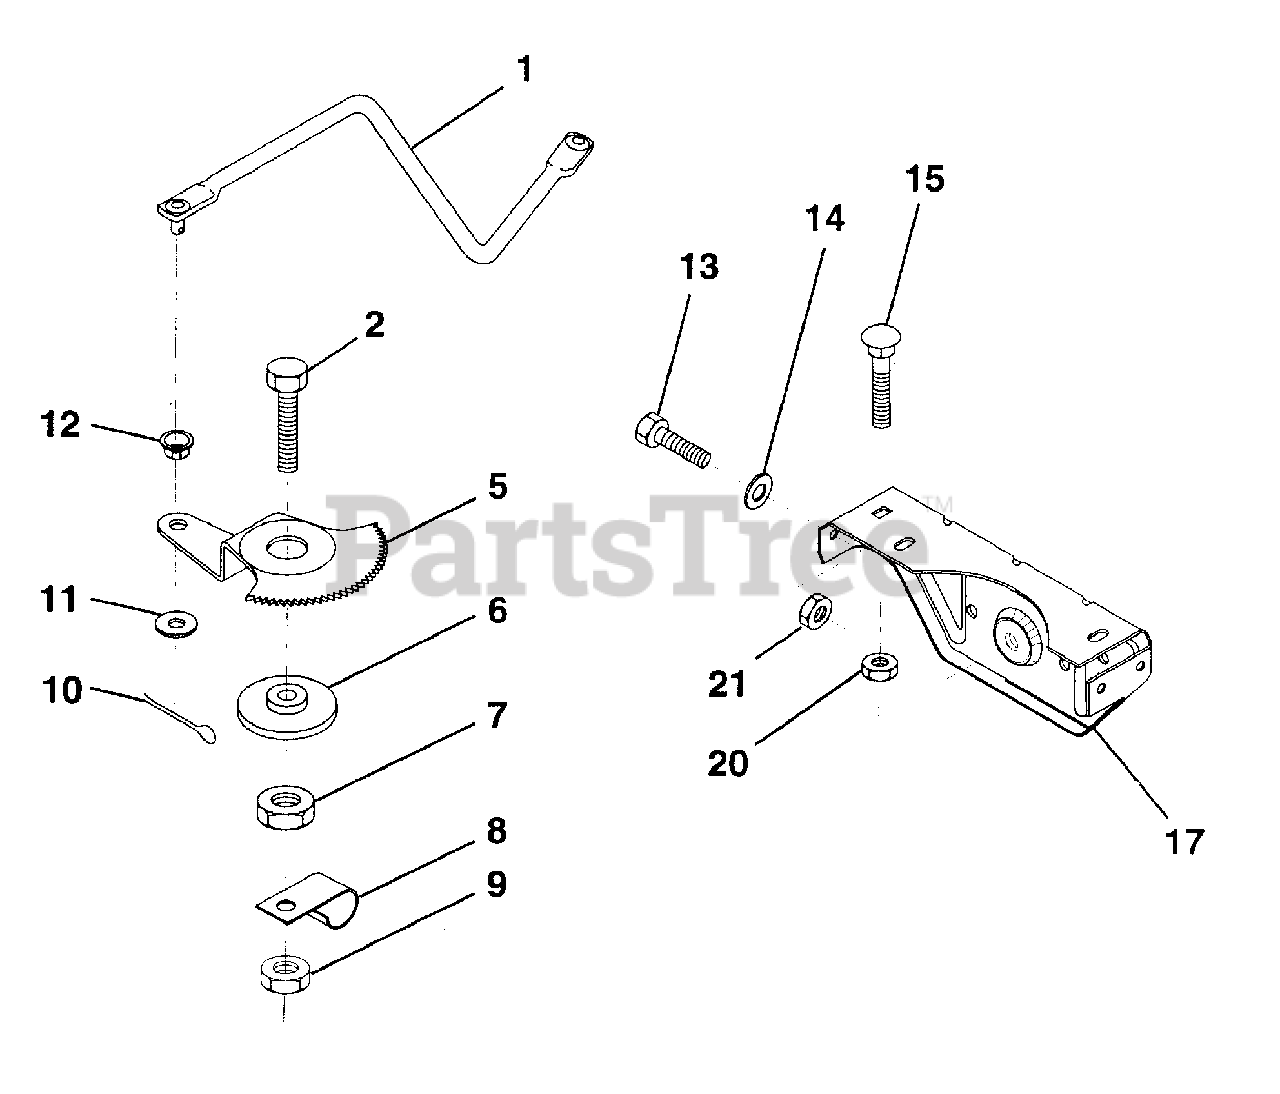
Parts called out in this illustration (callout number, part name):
1	Link, Drag
2	Bolt, Fin Hex 1/2-13 x 1-3/4
5	Gear, Sector
7	Nut, Heavy Hex Top Lock 1/2-13 UNC
8	Clip, Insulated
9	Nut, Crownlock 3/8-16
10	Pin, Cotter 1/8 x 3/4
11	Washer, 13/32 x 13/16 x 16 Ga.
13	Bolt, Hex Hd. 5/16-18 UNC x 3/4
14	Washer 11/32 x 7/8 x 16 Ga.
15	Bolt, Carriage 3/8-16 UNC x 3/4
17	Support, Front Axle
20	Nut, Crownlock 3/8-16 UNC
21	Nut, Crownlock 5/16-18
